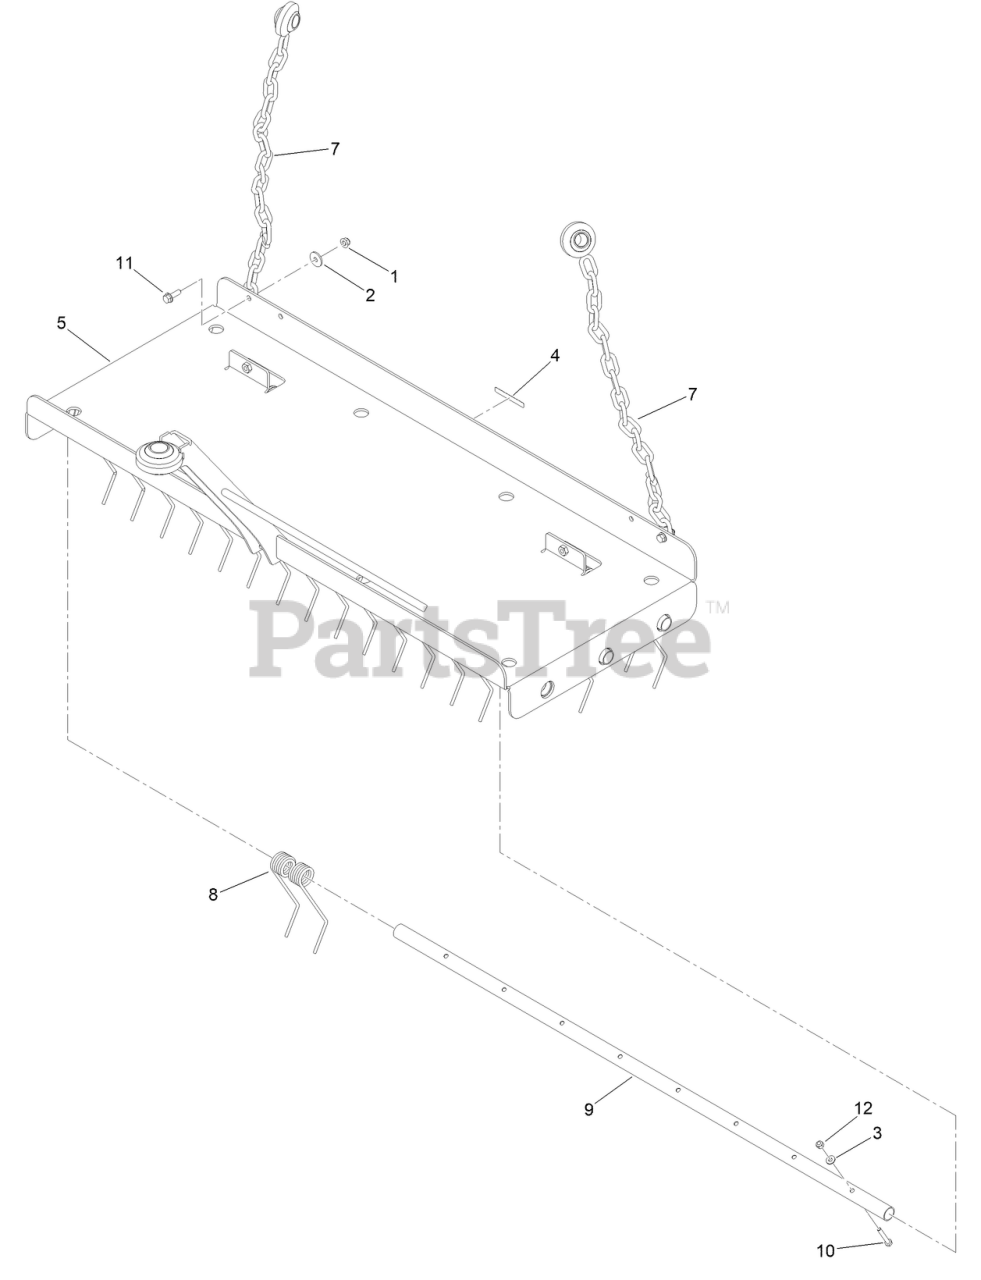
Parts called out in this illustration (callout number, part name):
1	NUT-HF, NI
2	WASHER-FLAT
4	DECAL-WARNING
5	PLATFORM-RAKE
7	RAKE BALL SOCKET AND CHAI
8	SPRING TINE\NGG187DT-NB
9	RAKE TUBE
10	SCREW-HH
11	SCREW-HH
12	NUT-LOCK, NI
